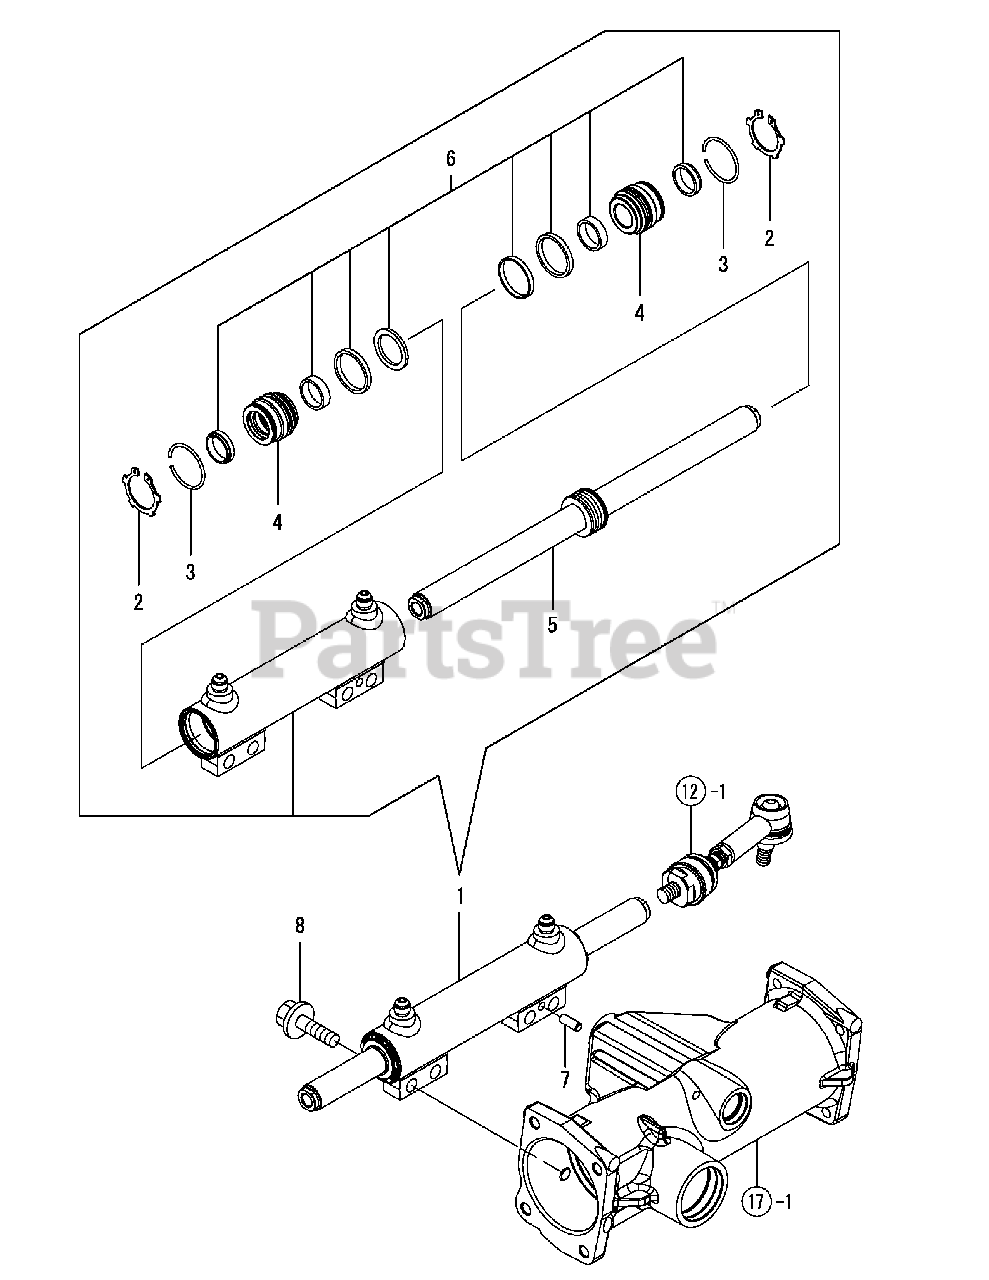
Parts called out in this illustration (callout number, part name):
1	CYLINDER ASSY, PST
3	RETAINING RING
7	PARALLEL PIN, M8X20
